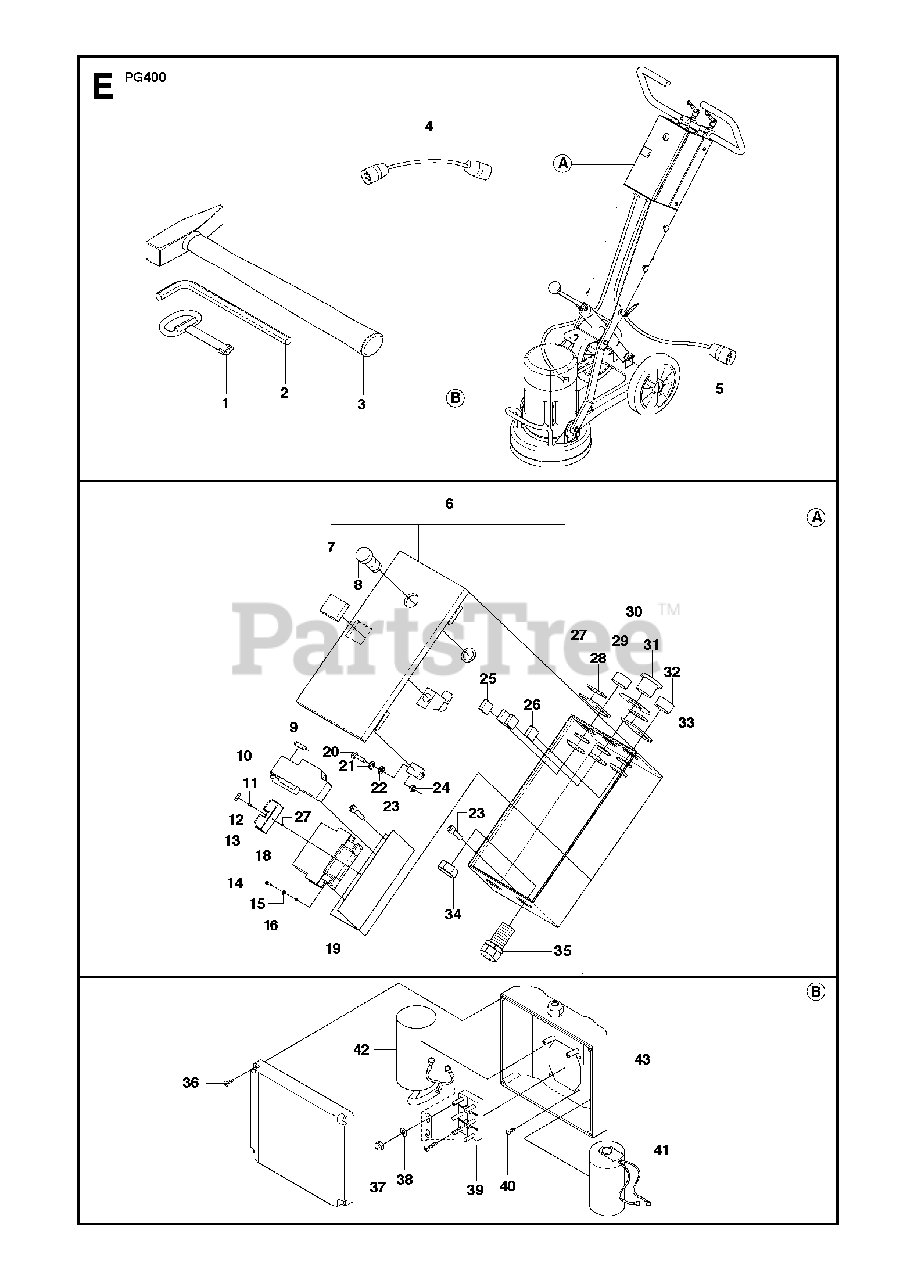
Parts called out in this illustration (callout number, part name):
5	CABLEIncl plug, EU, 3-Phase
5	CABLEIncl plug, EU, 1-Phase
5	CABLEIncl Plug, Brazil, 1-Phase
9	RESISTOREU.AUS,US(480V) 3-Phase
10	PROTECTIONEU.AUS,US(480V) 3-Phase
10	PROTECTIONUS (230V) 3-Phase
10	PROTECTION230V, 1-Phase
16	HEXAGON LOCKING NUT
17	HEXAGON LOCKING NUT
18	CONTACTOREU.AUS,US(480V)
18	CONTACTOR(230V) 1-Phase
20	SCREW EHHM
